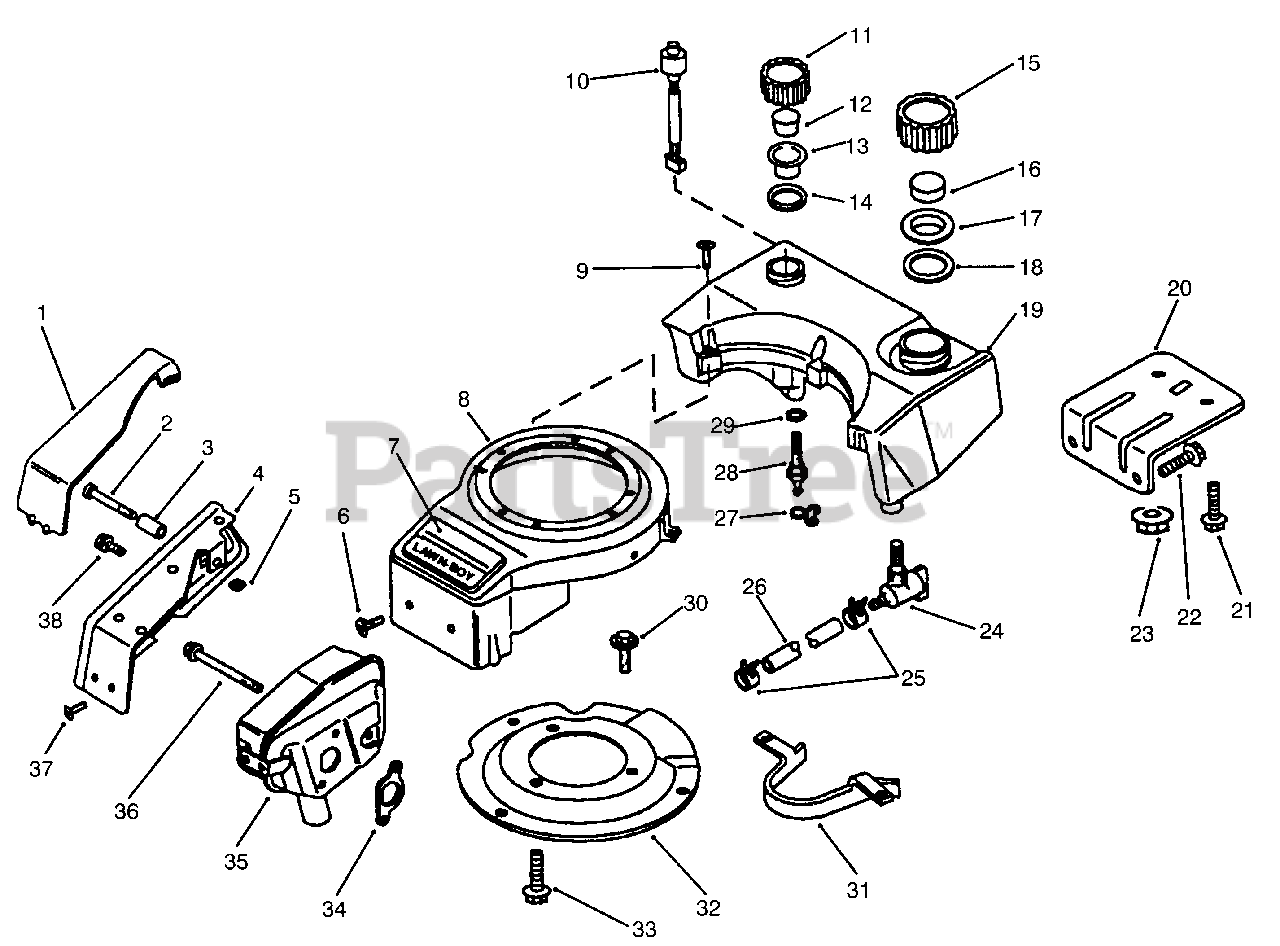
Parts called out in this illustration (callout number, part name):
1	Cover-Muffler
2	Screw-Muffler Guard
3	Spacer-Muffler Guard
4	Assembly-Muffler Guard (Incl. Ref. No. 1 & 5)
5	Pushnut
6	Screw-Shroud
7	Applique
8	Assy.-Shroud (Incl. Ref. No. 7)
9	Screw-Fuel Tank
10	Switch-Low Oil
11	Assembly-Oil Cap (Incl. Ref. No 12-14)
13	Cover-Baffle
15	Assembly-Fuel Cap (Incl. Ref. No.16-18)
17	Cover-Baffle
19	Assembly-Fuel/Oil Tank (Incl. Ref. No.10, 24, & 28-29)
20	Bracket-Fuel Tank
21	Screw-Fuel Tank Mount
22	Bolt-Bracket To Block
24	Fuel Shut-Off Valve
25	Clamp-Fuel Line
26	Fuel Line
27	Clamp-Oil Hose
28	Assembly-Oil Fitting (Incl. Ref. No.29)
30	Screw-Mtg Plate/Hsg.
31	Snubber-Belt
32	Plate-Engine Mounting
33	Screw-Mtg Plate To Eng.
34	Gasket-Exhaust
35	Muffler
36	Screw-Muffler
37	Screw-Muffler Guard
38	Screw-Muffler Guard
